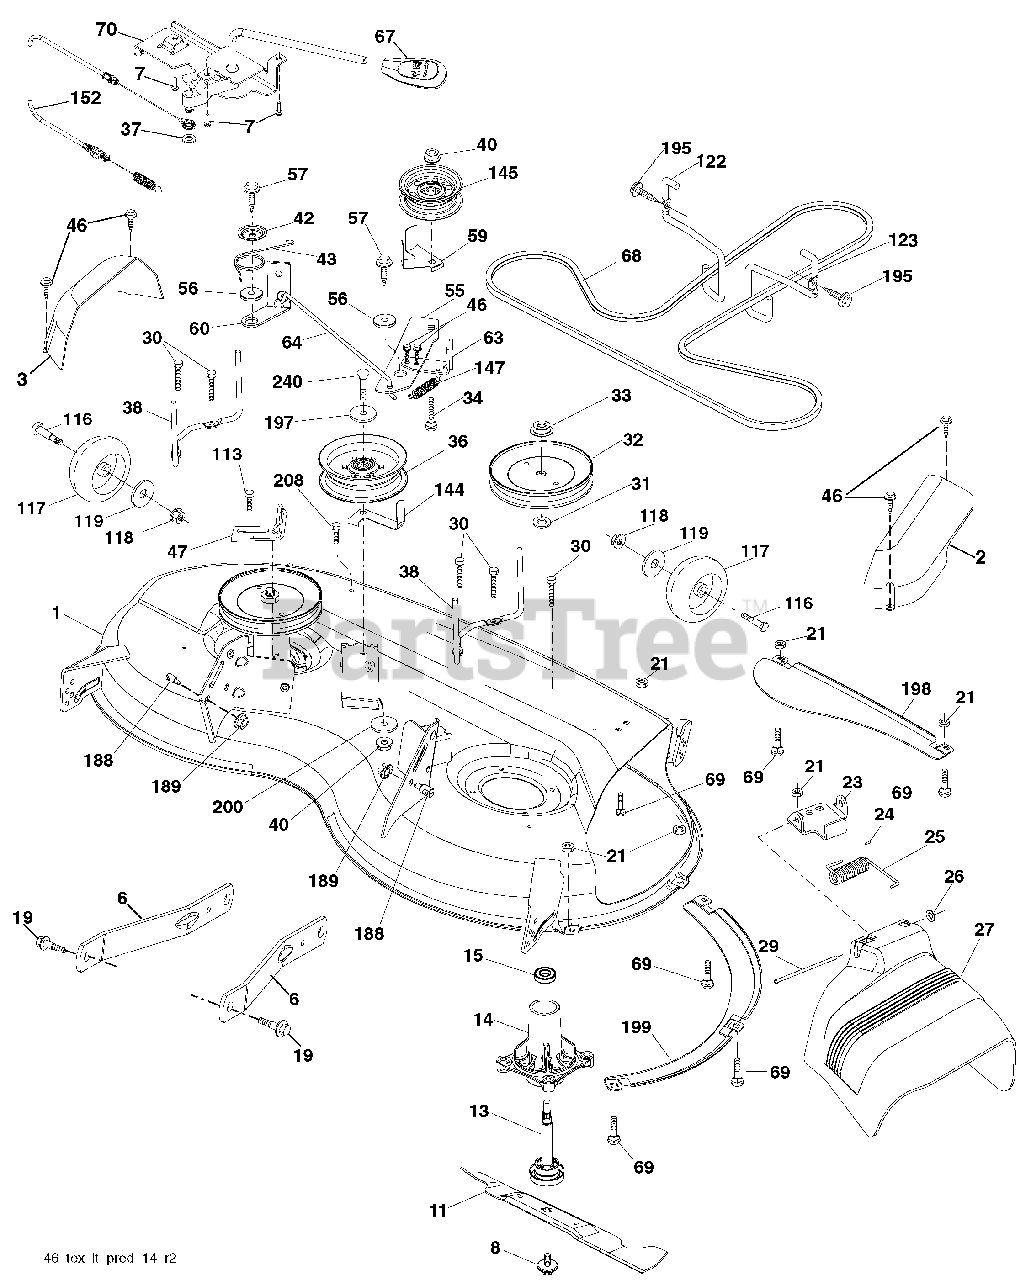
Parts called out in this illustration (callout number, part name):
1	Mower Housing
2	Cover Mandrel RH
3	Cover Mandrel LH
6	Arm Suspension
7	Screw #10 x 0.750 BOS Thread
8	Bolt/Washer asm 7/16-20 unf
11	Blade Mower
13	Shaft Assembly, Mandrel
14	Housing, Mandrel
15	Bearing, Ball, Mandrel
19	Bolt, Shoulder
21	Nut
23	Bracket, Deflector
24	Cap, Sleeve
25	Spring, Torsion, Deflector
26	Nut, Push
27	Shield, Deflector
29	Rod, Hinge
30	Screw Thdrol Rolling Wsh Hd
31	Washer, Spacer
32	Pulley, Mandrel
33	Nut, Toplock, Flanged
34	Bolt Carr Sh. 3/8-16 x 1-1/2 Gr. 5
36	Pulley, Idler, 4.50 RAW
37	Washer 13/32 x 13/16 x 16 Ga.
38	Keeper Belt LH Mandrel
40	Nut, Lock Flg. 3/8-16 unc
42	Spring Trosion Brake
43	Spring Torsion Retainer
46	Screw
47	Bracket Clutch Cable
55	Arm, Idler
56	Spacer, Retainer
57	Screw Hexwsh Thd 3/8-16 x 1
59	Guard, Tuv Idler (94)
60	Arm Brake Mower LH
63	Arm Brake Mower
64	Linkage Brake
67	Handle, Clutch Cable
68	Belt
69	Bolt
70	Clutch Asm.
113	Screw 5/16-18
116	Bolt, Shoulder
117	Wheel, Gauge
118	Nut Centerlock 3/8-16 unc
119	Washer 13/32 x 1-1/4 x 12 Ga.
122	Keeper Belt Eng. LH
123	Keeper Belt Eng. RH
144	Keeper Belt
145	Pulley Idler Primary
147	Spring Return
152	Cable Clutch Manual w/Spr.
188	Stud Fastener
189	Nut Lock Hex Flange
195	Screw 3/8-16 x 3/4
197	Washer 13/32 x 13/16 x 12 Ga.
198	Baffle Center Front
199	Baffle Front RH
200	Washer 13/32 x 1 x 1/2 11 Ga.
208	Screw Throl 3/8-16 x 1/2
240	Bolt 3/8-16 unc x 2-1/4 Gr. 5
240	Mandrel Assembly
240	Replacement Mower, Complete
